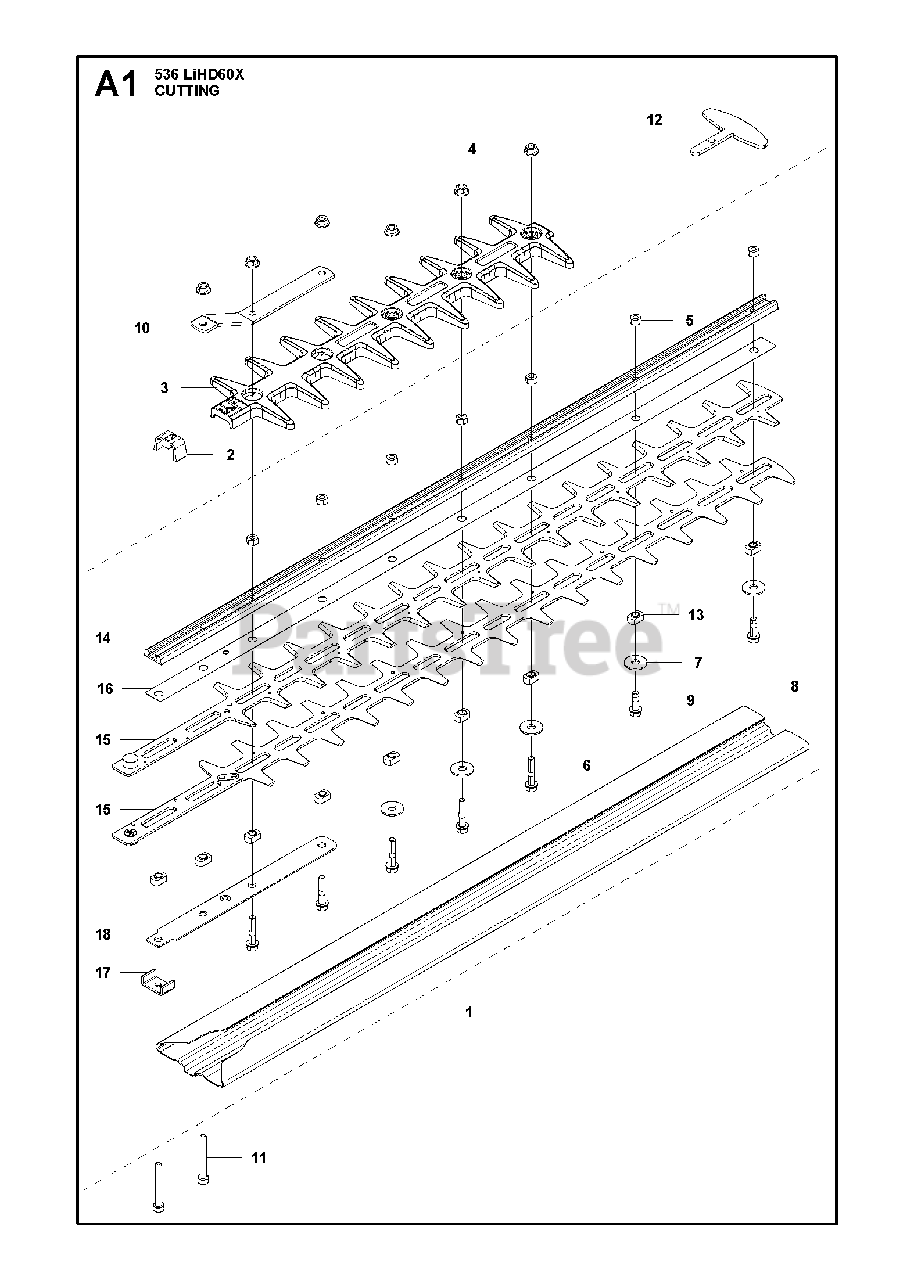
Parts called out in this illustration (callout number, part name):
1	CUTTING DECK LIHD HD60 INCR. S
3	PROTECTION ASSY BLADE
4	HEXAGON NUT FLANGE M5 8 ZN/FE
5	HEXAGON NUT ISO 4032-M5-10
6	SCREW IHSCFM M5X25 10.9 ZN/FE
7	WASHER 6,4X18X1,5
8	TRANSPORT GUARD CUTTING DECK H
9	SCREW IHSCFM M5X16 10.9 ZN/FE
10	SUPPORT CUTTING DECK
11	SCREW IHSCT EN ISO 4762 / DIN
12	PROTECTION BLADE TIP
13	SPACER HEDGE TRIMMER
14	BAR CUTTING DECK LIHD60
15	BLADE ASSY HD60 SLOTS INCR.
16	WEAR PLATE HD60
17	BRACKET
18	BAR
